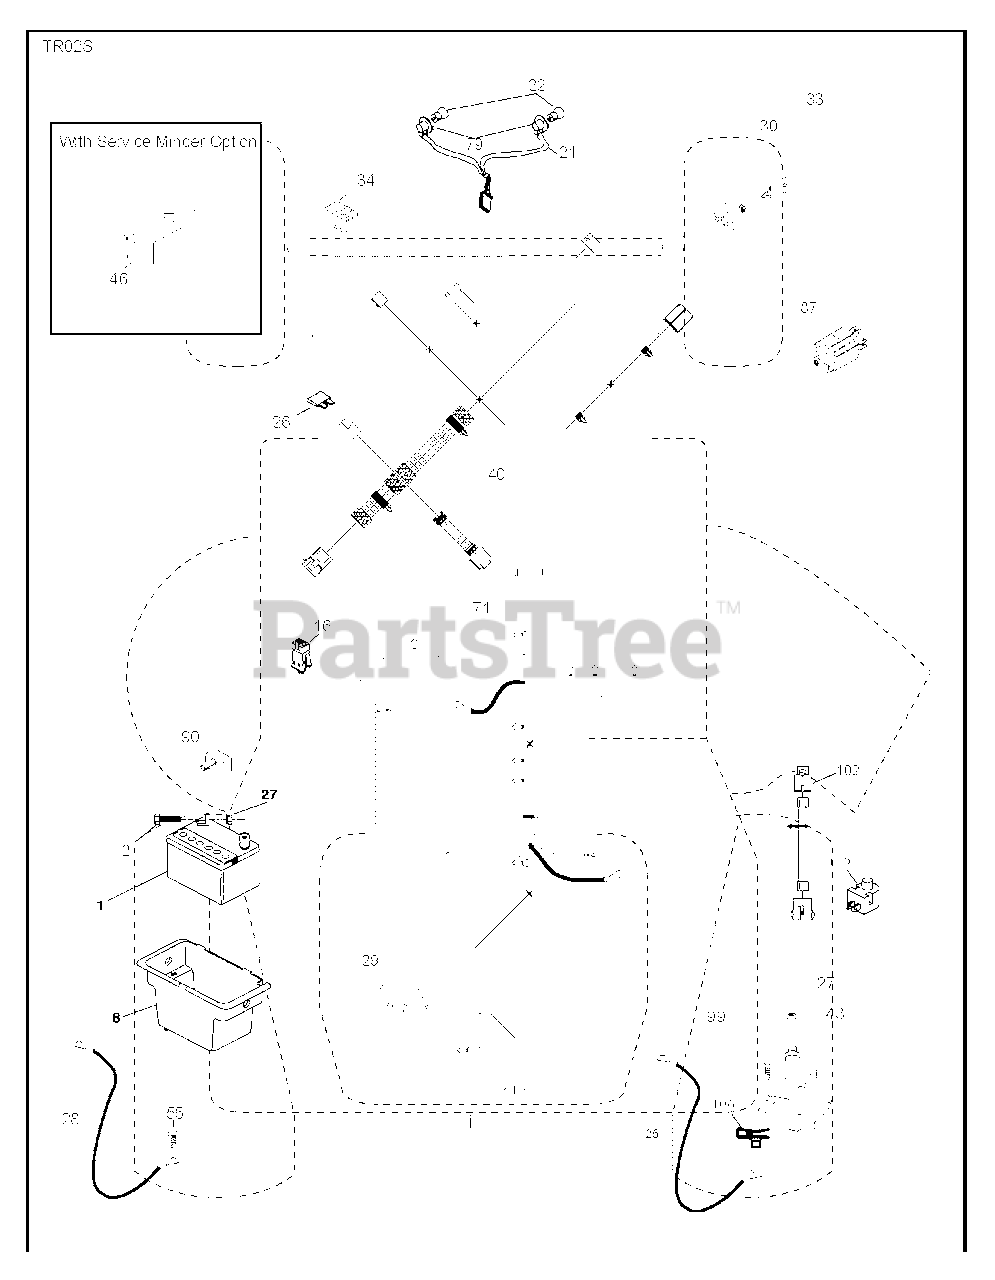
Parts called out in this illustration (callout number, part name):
16	SWITCH INTERLOOK PUSH-IN
22	LIGHTBULB
26	FUSE 20AMP
29	SWITCH.SEAT.DELTA.OPC.
30	SWITCH.IGN.DELTA.W.LGH.ROS
33	KEY.CHAIN.BLISTER.PACK.GEN.USA
34	SWITCH LT
43	SOLENOID.W/BRASS.PLUNG
79	BULB HOLDER ASM.
90	COVER.TERMINAL.BATTERY
99	SCREW HEXWSHR 1/4-20X3/4
102	HARNESS PIGTAIL PCH TEX ROS
105	REVERSE SWITCH
106	1/4-20 U NUT
